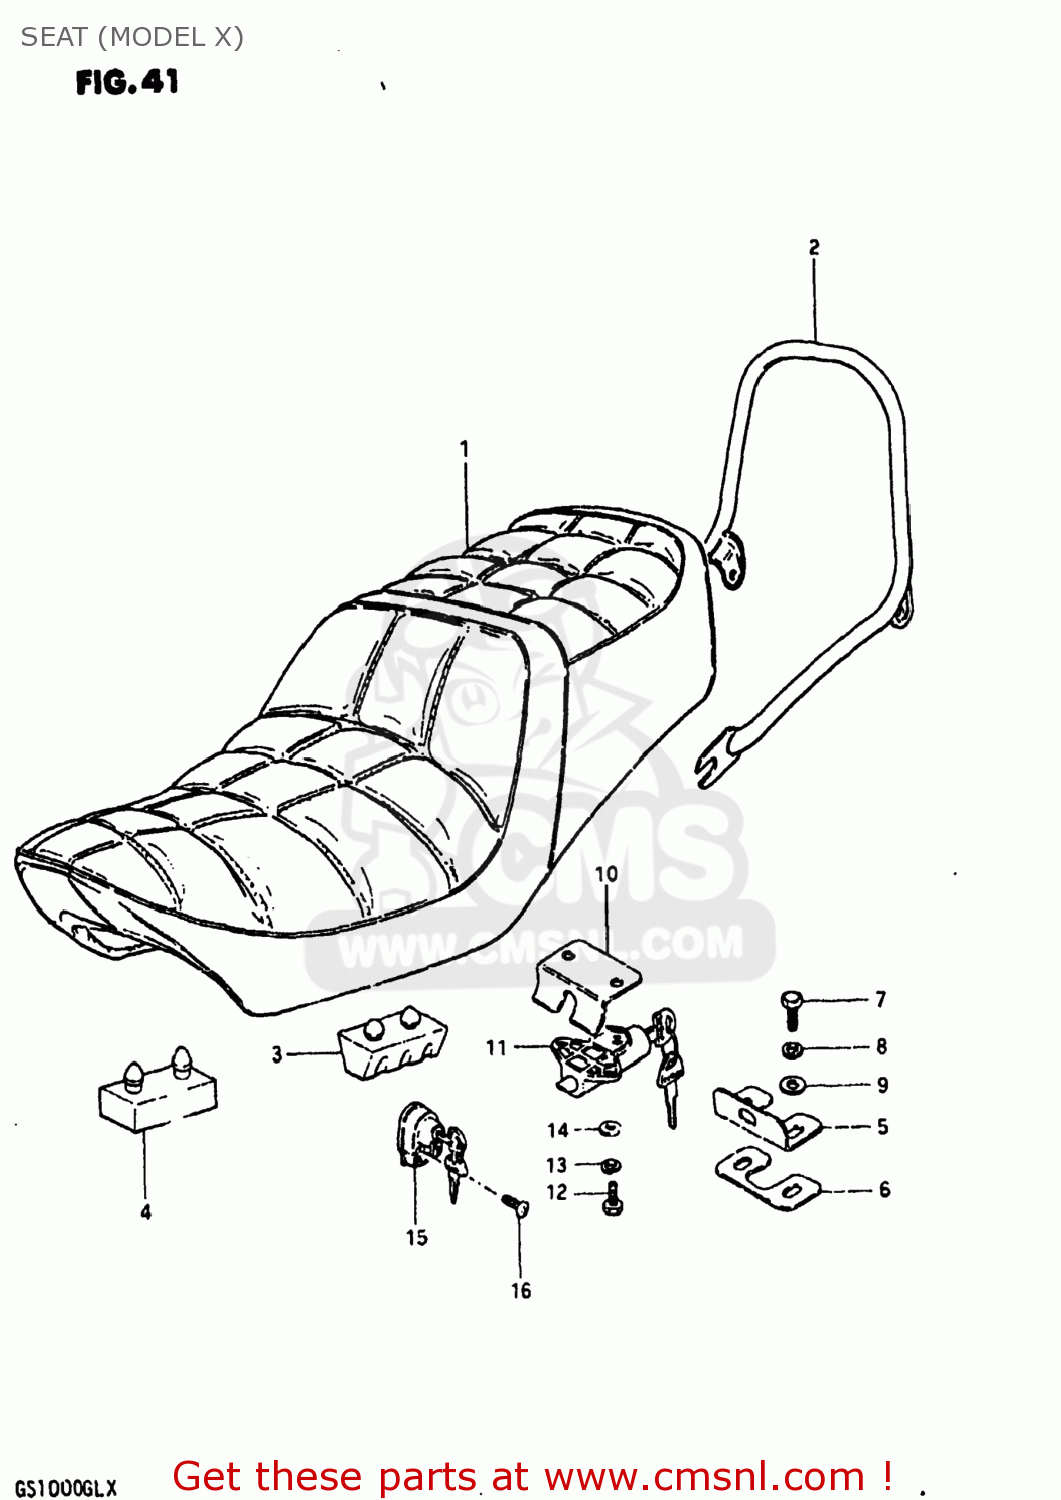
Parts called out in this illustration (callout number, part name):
1	SEAT ASSEMBLY
2	HANDLE,PILLION RIDER
3	CUSHION,SUPPORT(50X25X32)
4	CUSHION
5	STRIKER,SEAT LOCK
6	SHIM,SEAT LOCK STRIKER
7	BOLT, UPPER
8	LOCK WASHER
9	WASHER
10	PLATE,SEAT LOCK
11	LOCK ASSEMBLY,SEAT
12	BOLT
13	LOCK WASHER
14	WASHER 6MM
15	LOCK ASSY,HELMET
16	BOLT 5X25
